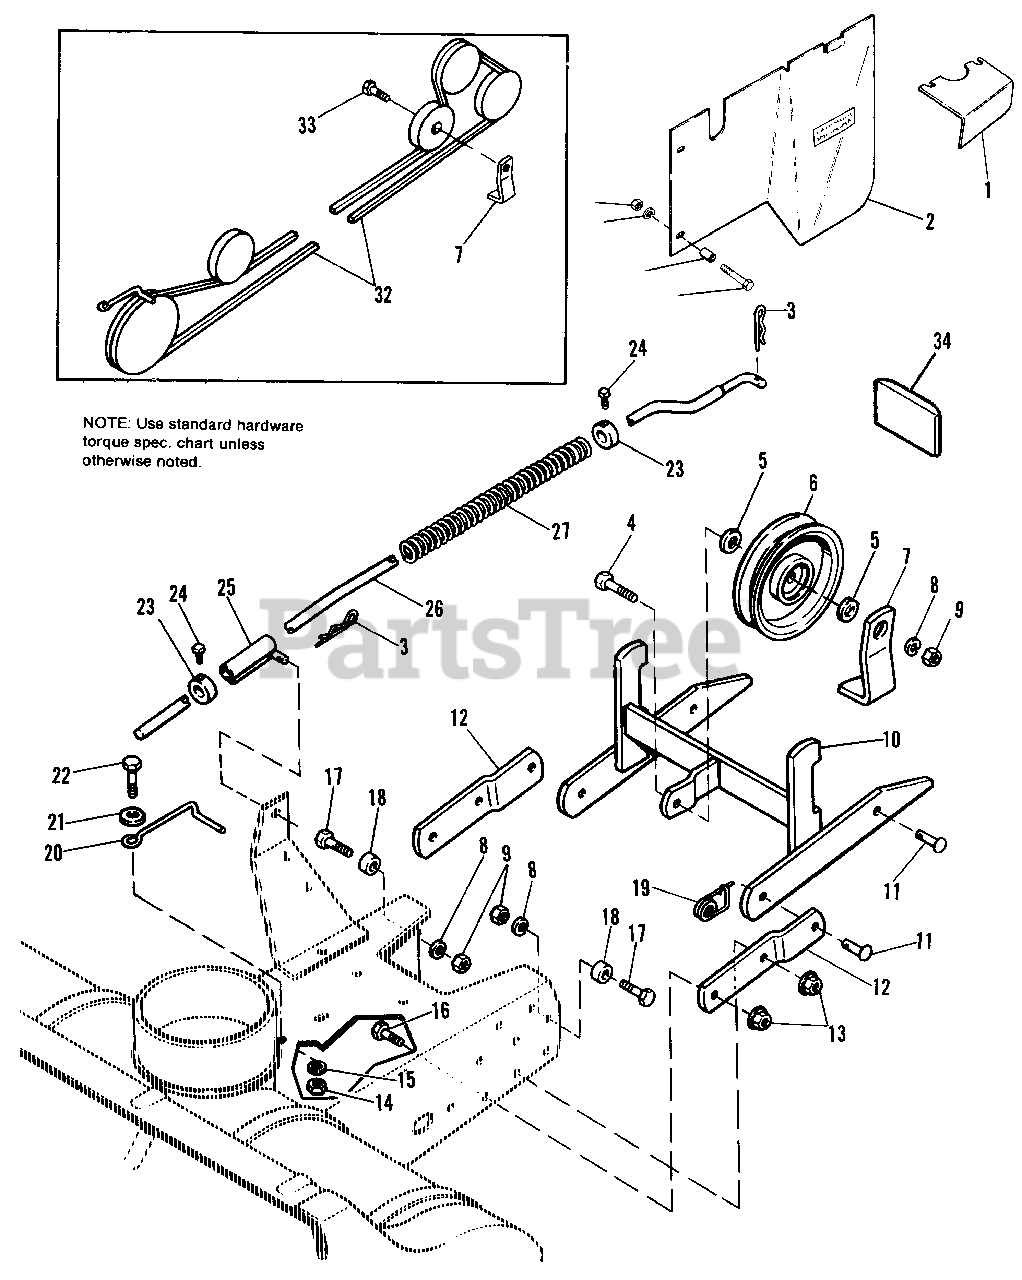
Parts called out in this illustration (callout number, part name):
1	SHIELD, Carburetor
2	DEFLECTOR ASSY
3	CLIP, Spring
4	CAPSCREW, Hex Hd, 3/8-16 x 2
5	WASHER, Plain, 3/8
6	PULLY, Idler
7	STOP, Belt
8	LOCKWASHER, 3/8
9	NUT, Hex, Full, 3/8-16
12	CLIP, Frame
13	LOCKNUT, Hex, Flange, 7/16-14
14	NUT, Hex, Full, 5/16-18
15	LOCKWASHER, 5/16
16	CAPSCREW, Hex Hd, 7/16-14 x 1
17	CAPSCREW, Hex Hd, 3/8-16 x 1-1/4
19	CLIP, Spring
21	WASHER, Plain, 5/16
22	CAPSCREW, Hex Hd, 5/16-18 x 3/4
23	COLLAR, Set
24	SETSCREW, 5/16-18 x 1/2
25	GUIDE ASSY, Rod
28	CAPSCREW, Hex Hd, 1/4-20 x 1
29	SPACER
30	LOCKWASHER, 1/4
31	NUT, Hex, Full, 1/4-20
32	V-BELT, Drive
33	CAPSCREW, Hex Hd, 3/8-16 x 2-1/4
34	REFLECTOR, Rear
